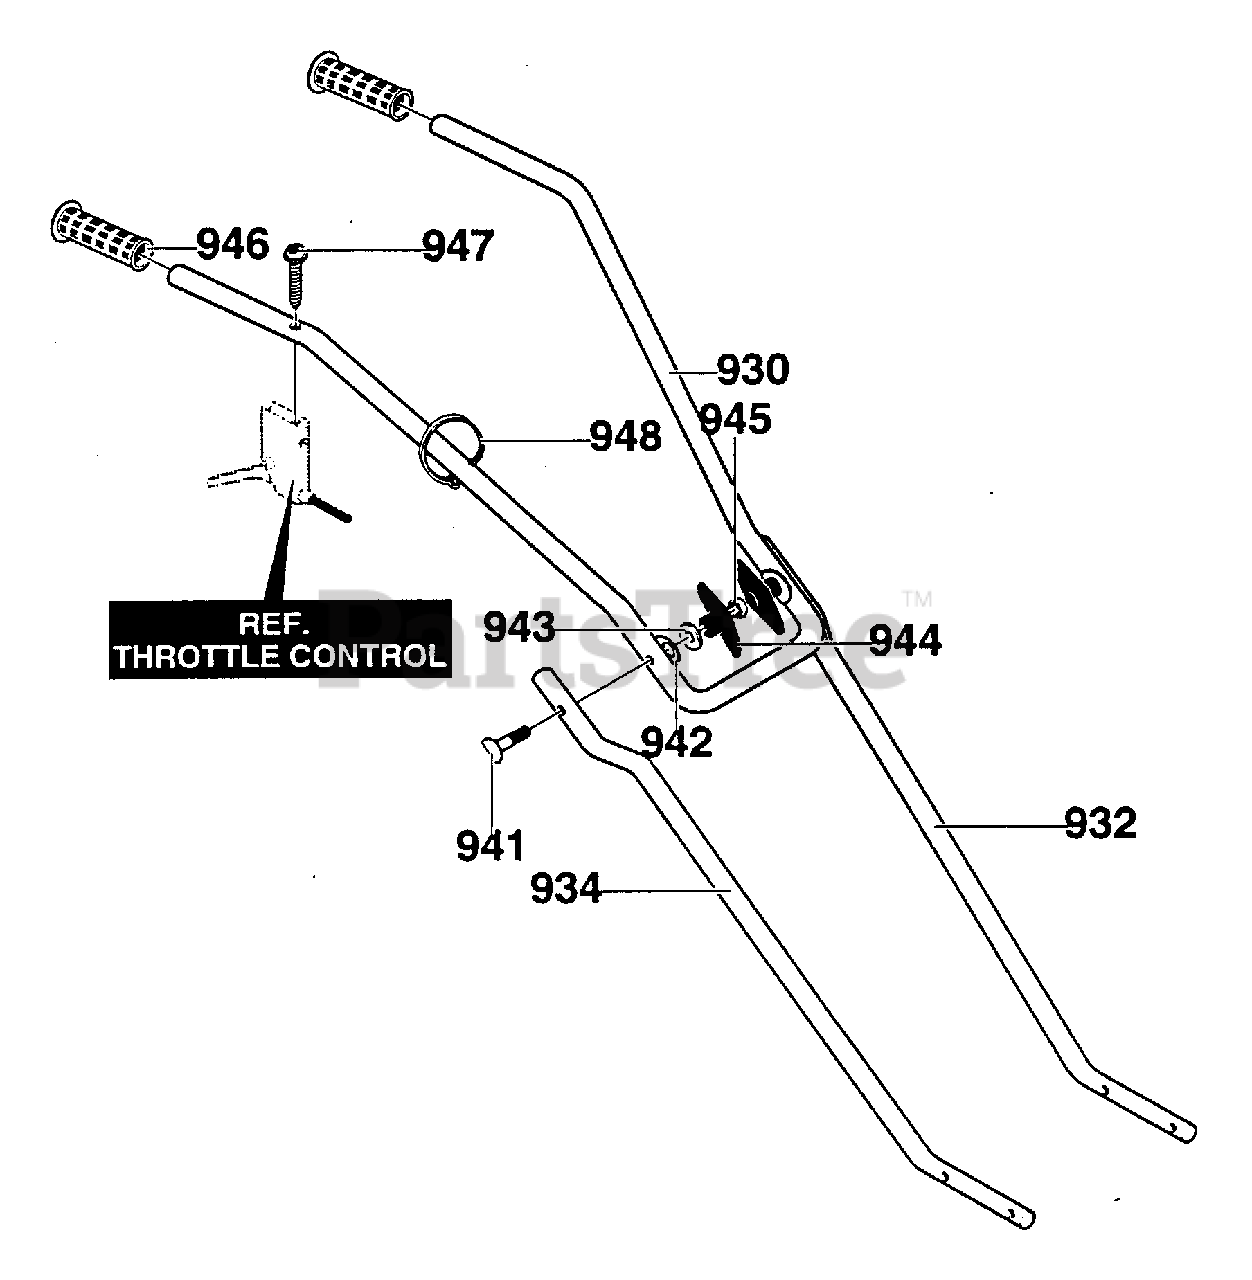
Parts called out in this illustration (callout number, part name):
930	HANDLE, UPPER .75 X 18 GASTEEL
932	HANDLE, LOWER LH
934	HANDLE, LOWER RH
941	BOLT, 5/16-18X1.63 CARRSP
942	WASHER,.343ID X 1.OX.062 FORM
943	WASHER, FLAT .344 X .69 X.065
944	KNOB, T 2BLADE W/516-18 NUT
945	NUT, 5/16-18 REGHEX
946	GRIP, HAND
947	SCREW, 10-16 X 1.50 WAHHTAP
948	TIE, CABLE BLACK NYLON 5.62L
